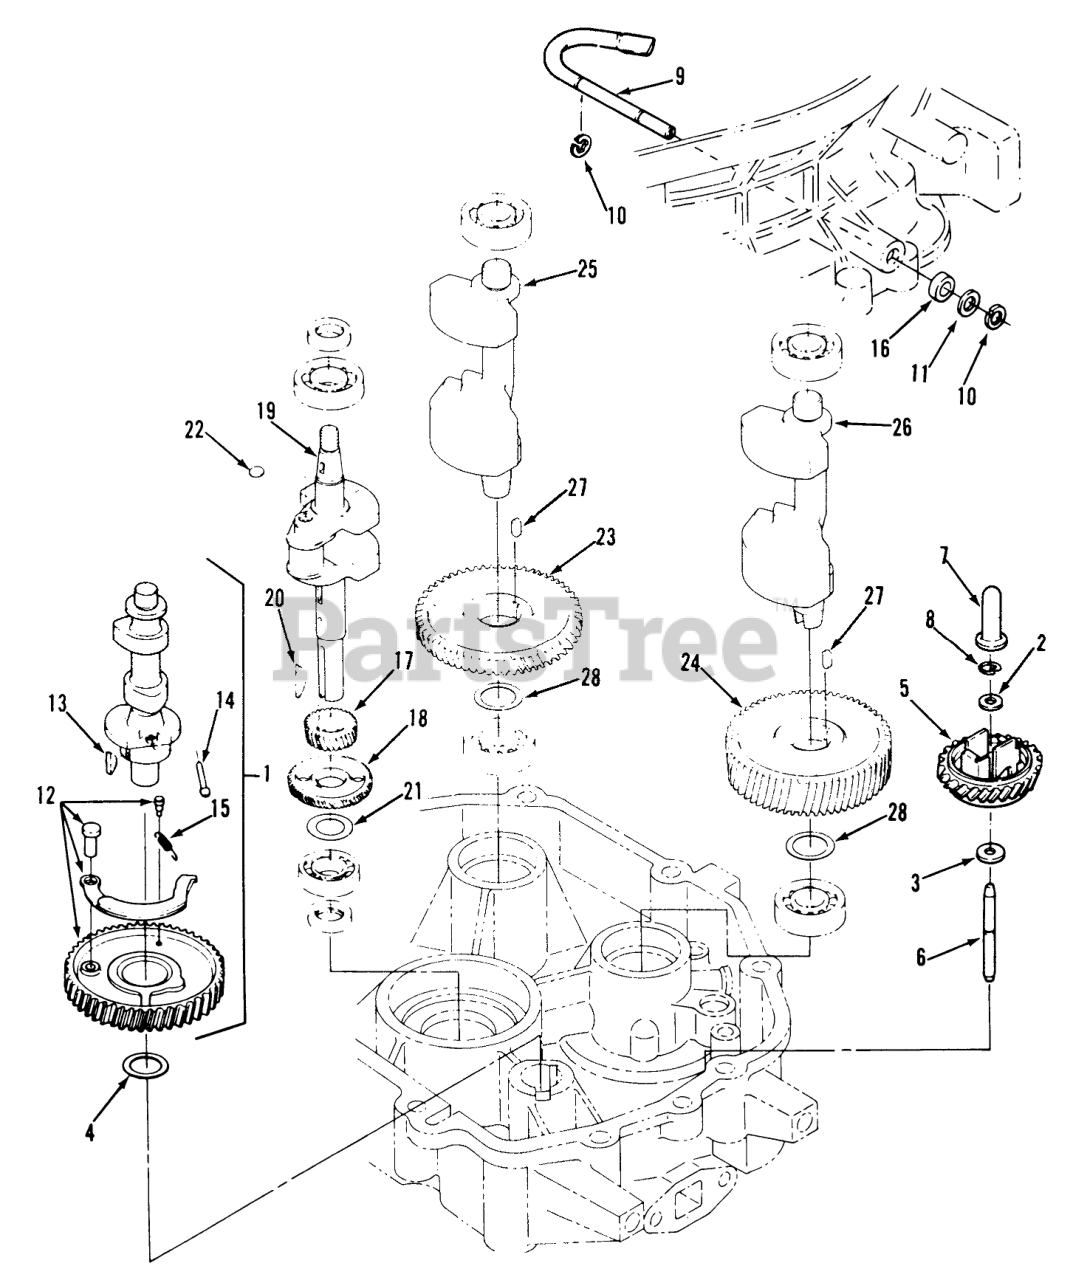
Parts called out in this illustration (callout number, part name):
1	CAMSHAFT-ASS'Y
2	WASHER-1.6MM THK
3	WASHER-1MM THK
4	SHIM-CAMSHFT 0.5MM
5	Gear (Includes shafts and weights)
6	SHAFT-GOVERNOR
7	Sleeve
8	STOP-GOVERNOR
9	SHAFT-GOVERNOR LEVER
10	CLIP-RETAINER
11	Nut-M8
12	CAMGEAR ASS'Y
13	KEY-CAMGEAR
14	PIN-DECOMPRESSION
15	SPRING-DECOMPRESSION
16	SEAL-GVR SHAFT LEVER
17	GEAR-CRANKSHAFT
18	GEAR-BALANCER
19	Crankshaft
20	KEY-CRANKSHAFT GEAR
21	SHIM-CRANKSHFT 0.2MM
22	PLUG-EXPANSION
23	GEAR-BALANCER
24	GEAR-BALANCER
25	SHAFT-BALANCER
26	SHAFT-BALANCER
27	KEY-BALANCER GEAR
28	SHIM-BAL SHAFT 0.5MM
